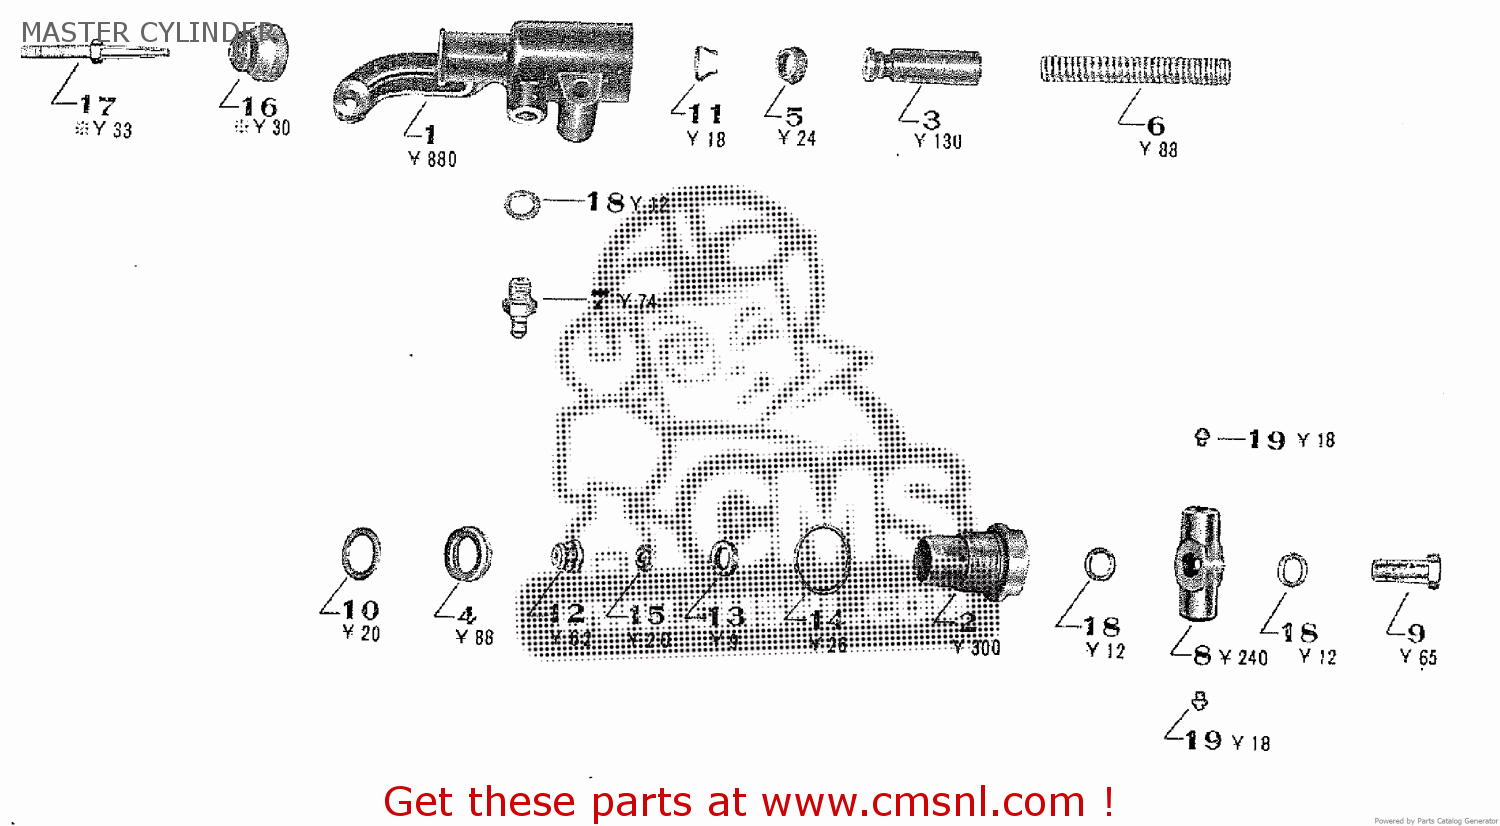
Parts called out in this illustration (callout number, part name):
1	CYLINDER
2	CYLINDER CAP
3	PISTON
4	PRIMARY RING CUP
5	SECONDARY PACKING
6	RETURN SPRING
7	CYLINDER PLUG
8	UNION
9	UNION BOLT
10	CUP SPACER
11	PISTON STOPPER
12	OUTLET VALVE COMP.
13	OUTLET VALVE SHEET PACKING
14	CYLINDER CAP PACKING
15	OUTLET VALVE SPACER
16	CYLINDER BOOT
17	PISTON PUSH ROD
18	UNION PACKING
19	TUBE JOINT SHEET
